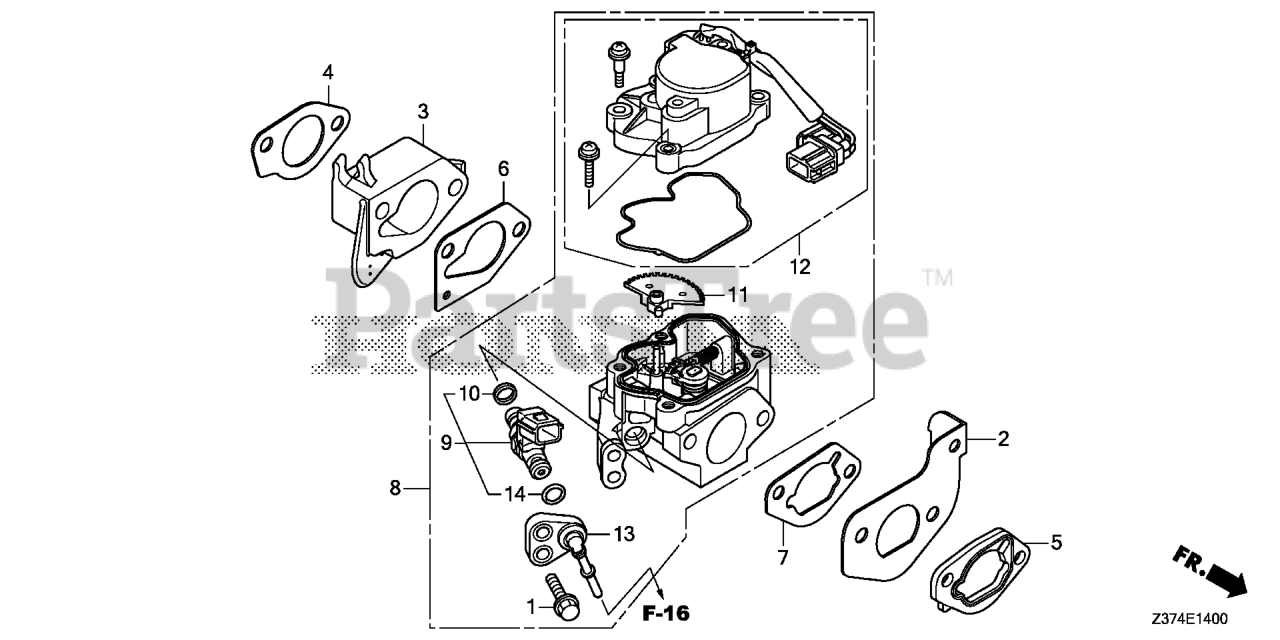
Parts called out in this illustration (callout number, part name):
1	BOLT, FLANGE (5X20)
2	HOLDER, CONNECTOR
3	INSULATOR, THROTTLE BODY
4	GASKET, CARBURETOR INSULATOR
5	SPACER, CARBURETOR
6	GASKET, THROTTLE BODY
7	GASKET, AIR CLEANER
8	BODY ASSY., THROTTLE (BLH0A A)
9	INJECTOR ASSY., FUEL
10	RING, SEAL
11	GEAR, MIDDLE
12	COVER ASSY., MOTOR
13	JOINT, INJECTOR
14	O-RING (6.3X2.2)
